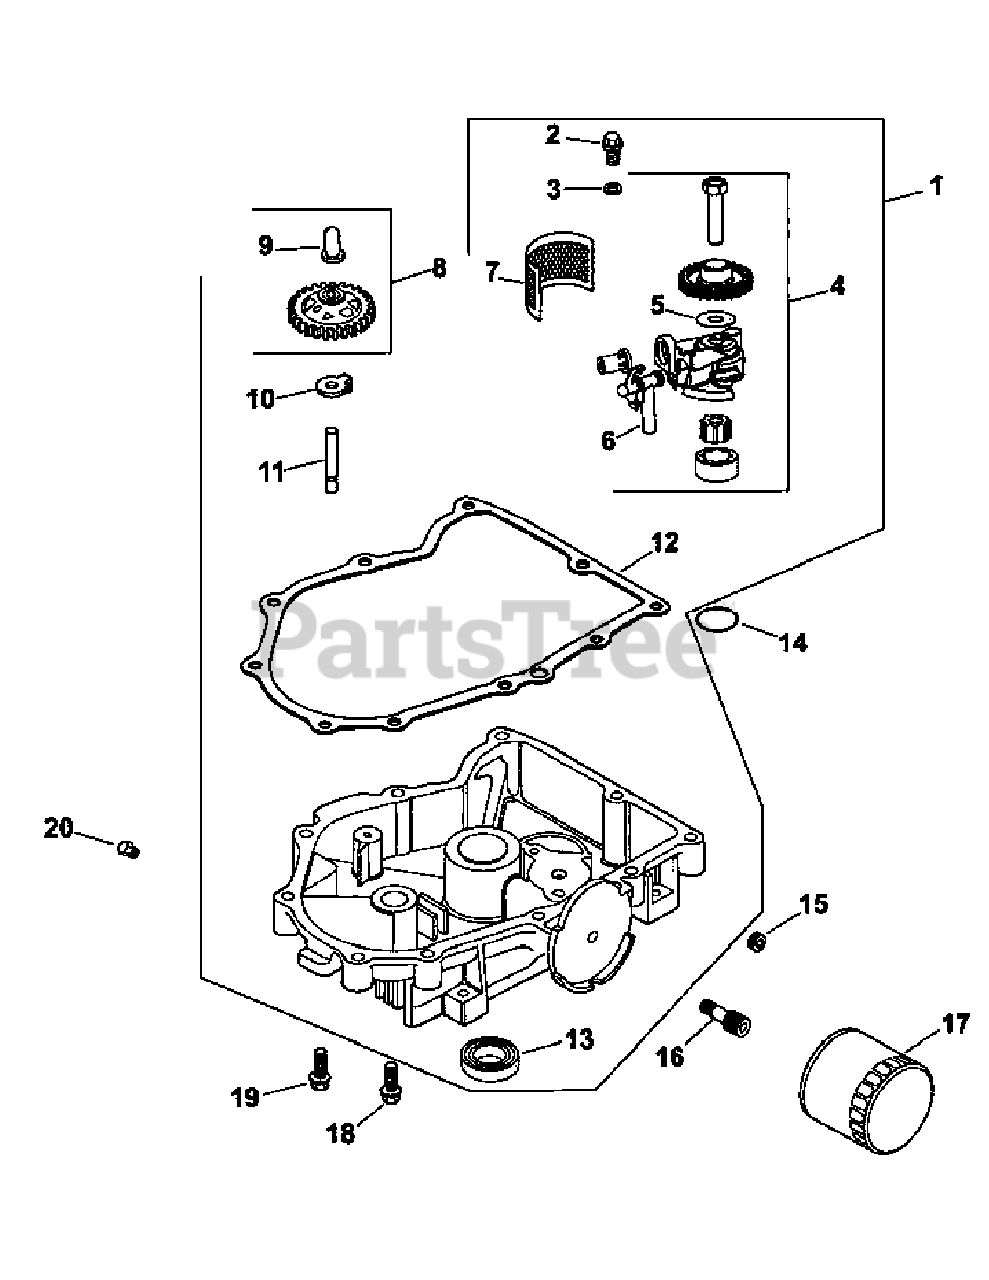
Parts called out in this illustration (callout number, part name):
1	Oil Pan w/Gasket Kit
2	Hex Flange Screw (M6 x 1.0 x 25)
3	Plain Washer 6mm
4	Oil Pump Assembly
6	Oil Pickup Tube
8	Governor Gear Kit
9	Governor Regulating Pin
11	Governor Gear Shaft
12	Oil Pan Gasket
13	Oil Seal (PTO End)
15	Hex Plug 3/8"
16	Oil Filter Nipple
18	Hex Flange Screw (M8 x 1.25 x 45)
19	Hex Flange Screw (M8 x 1.25 x 45)
20	Plug, Pipe 3/8" Hex Head
